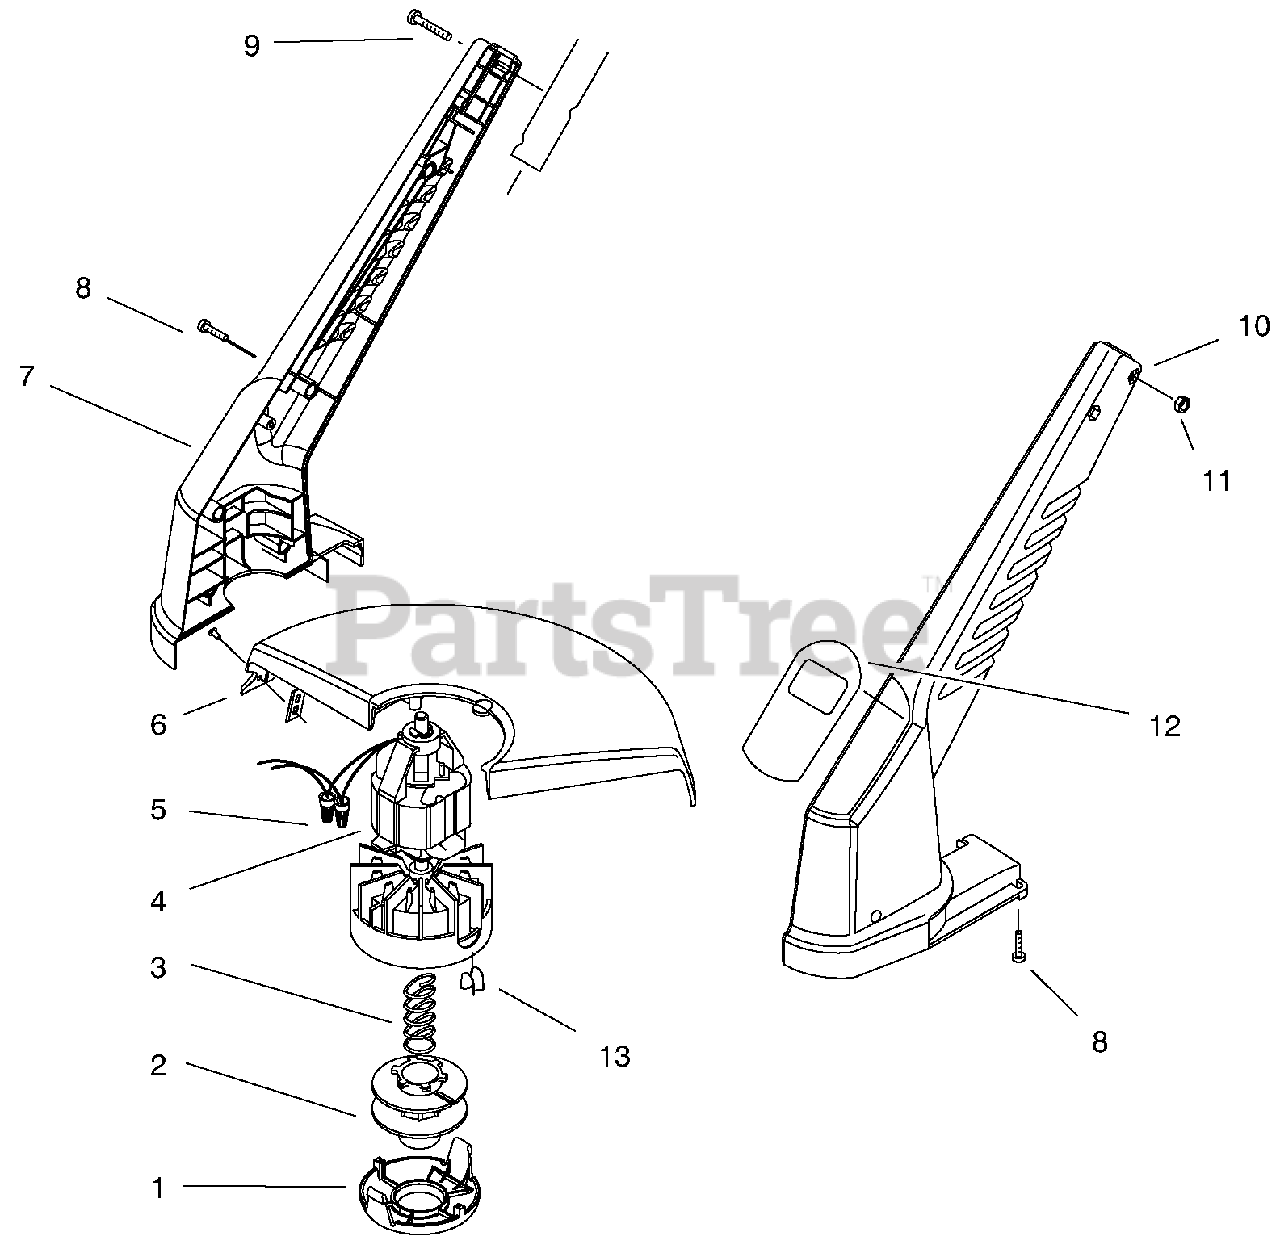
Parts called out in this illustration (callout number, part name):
4	Motor Assembly (Incl. Ref. #13)
5	Connector-Wire Nut
6	Shield-12"
7	Housing R.H.
8	Screw-Pan Hd. Tapping
9	Screw-Pan Hd.
10	Housing L.H.
12	Decal-12" Trimmer
